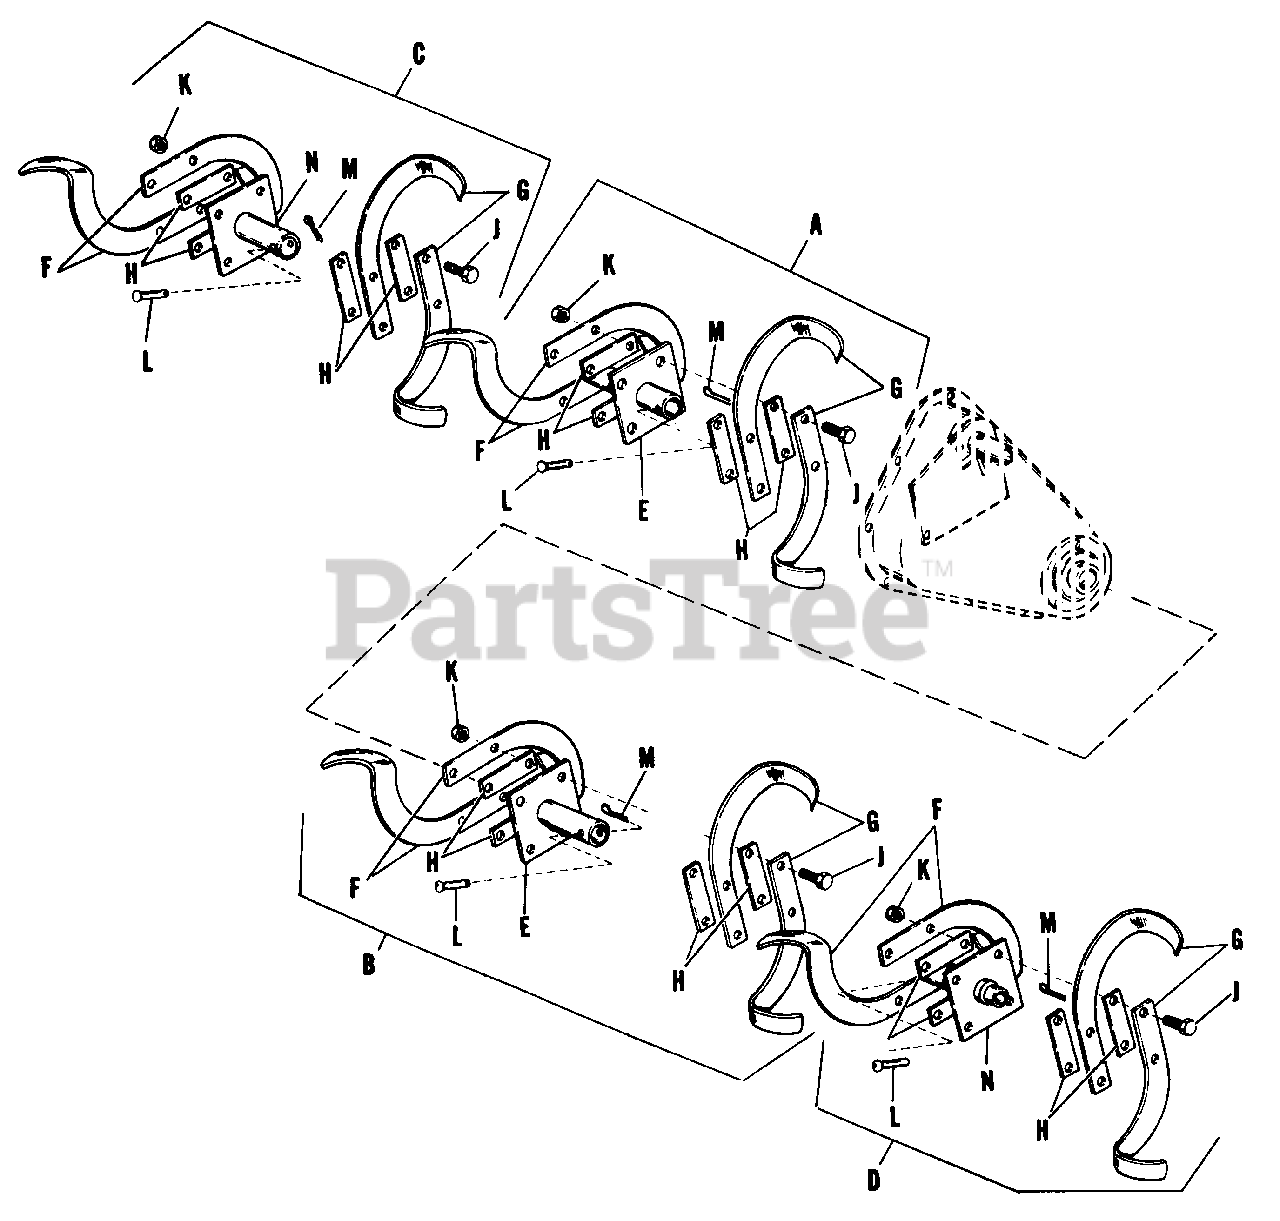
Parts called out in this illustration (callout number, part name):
A	Blade Assembly, Right Hand Inner Tine
B	Blade Assembly, Left Hand Inner Tine
C	Blade Assembly, Right Hand Outer Tine
D	Blade Assembly, Left Hand Outer Tine
E	Plate Assembly, Tine, Inner
F	Blade, Tine, Right Hand
G	Blade , Tine Left Hand
J	Capscrew, Hex, 7/16"-20 NC x 1 3/4" lg
K	Nut, Lock, Hex, Full, 7/16"-20 NC
L	Pin, Tine Shaft
M	Pin, Cotter, 1/8" diameter
N	Plate Assembly, Tine, Outer
